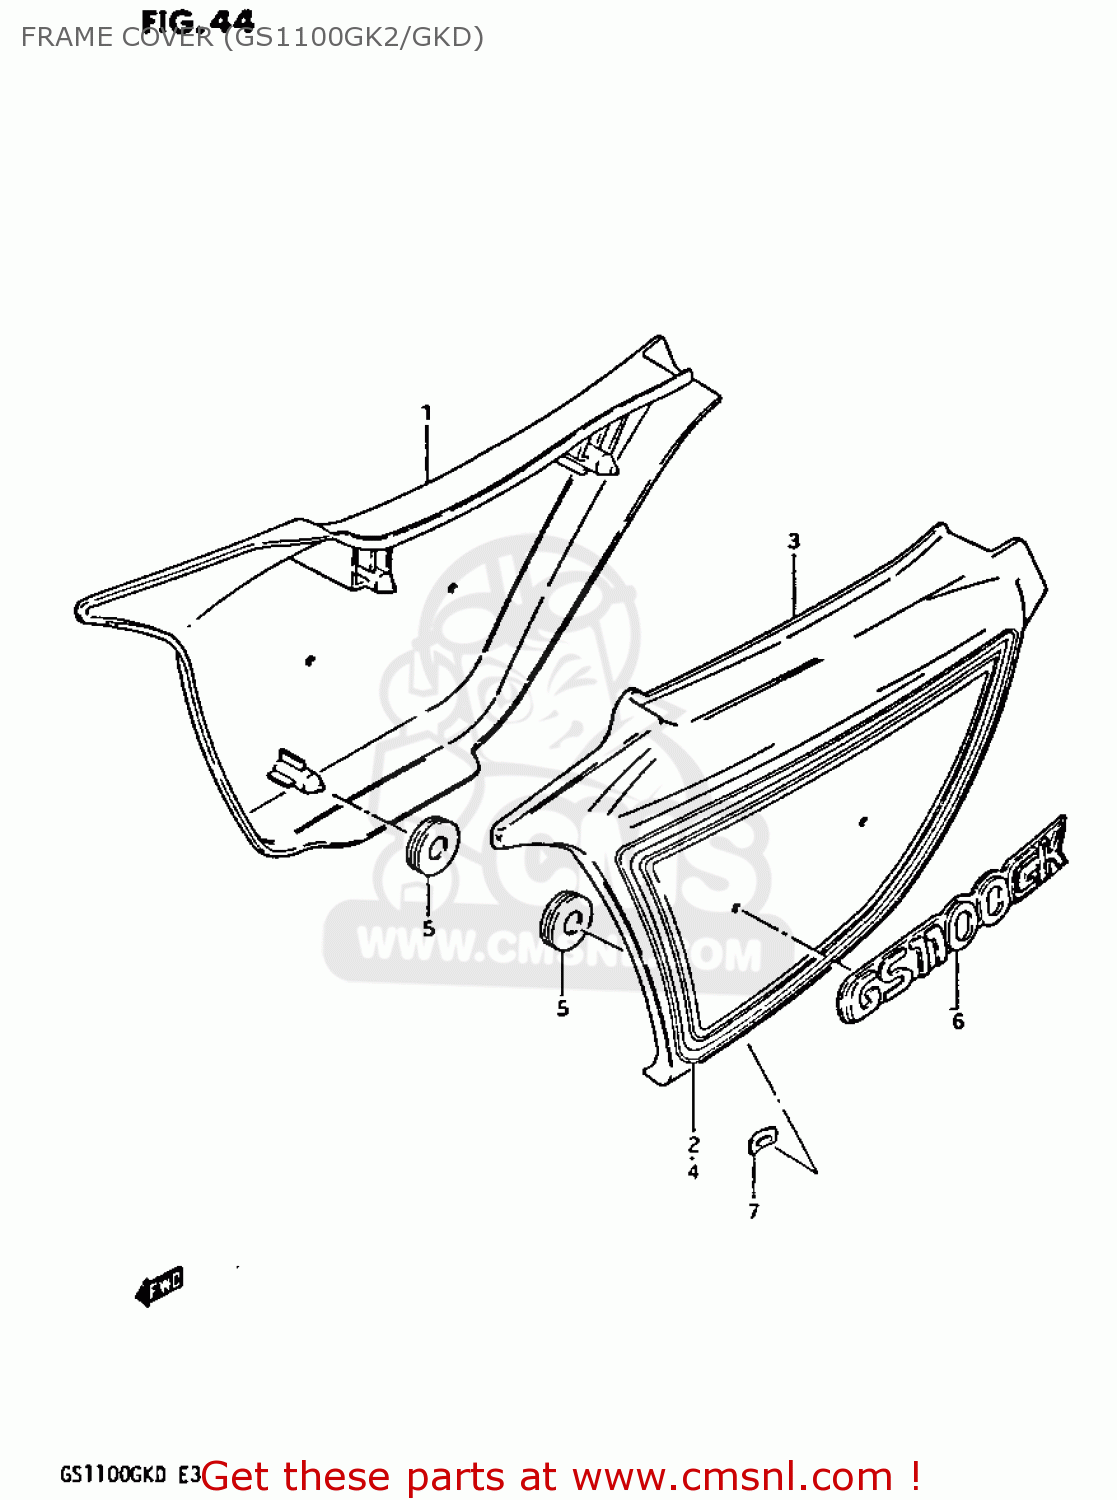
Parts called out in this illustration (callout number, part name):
1	COVER,FRAME,R
2	TAPE SET,FRAME COVER
3	COVER,FRAME,L
4	TAPE SET,FRAME COVER
5	CUSHION
6	EMBLEM,FRAME COVER
7	NUT
